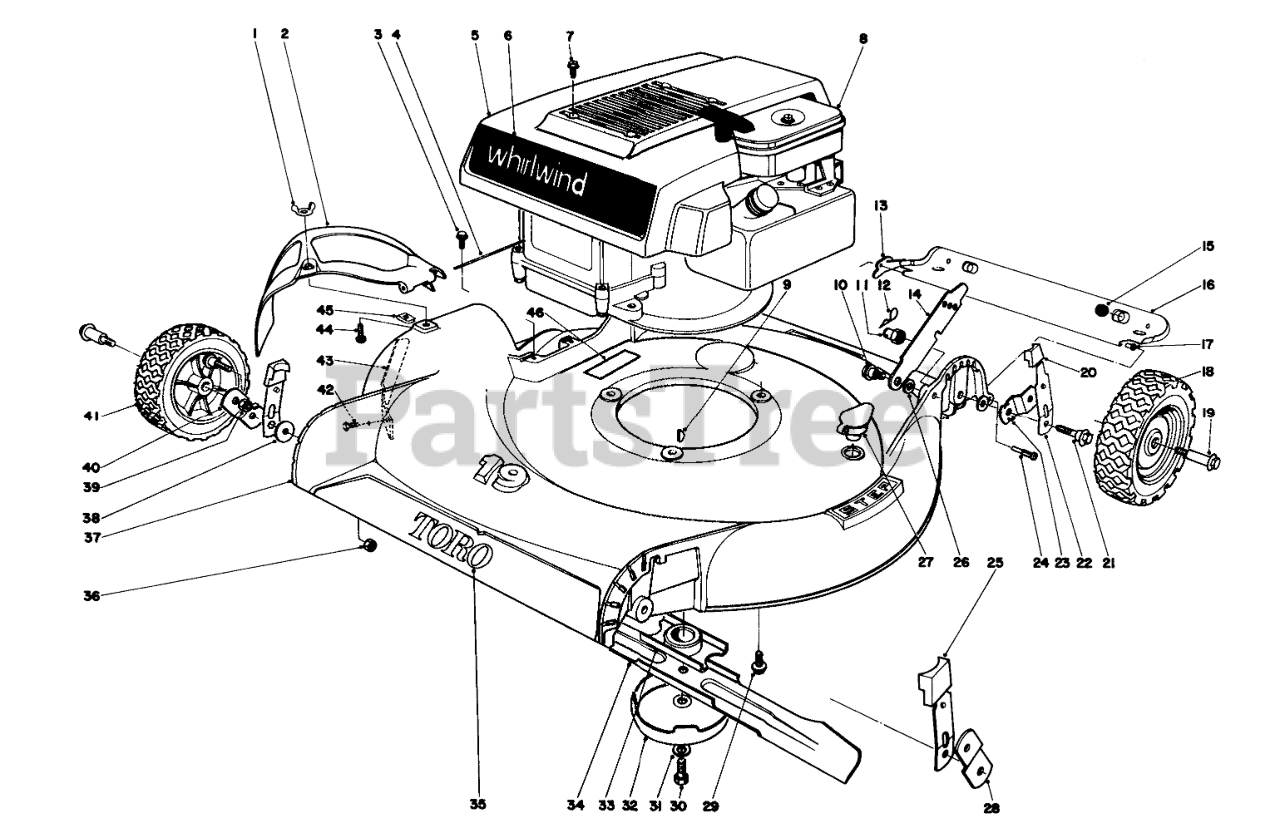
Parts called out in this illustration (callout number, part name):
1	NUT-WING SPECL
2	Deflector
3	SCREW
4	HINGE PIN
5	Shroud
6	Decal Whirlwind
7	8X1/2 SELF TAP SCREW
8	Engine (Model 16073)
9	KEY-WOODRUFF
10	SCREW-SHOULDER
11	HANDLE PIVOT NUT
12	Hair Pin Cotter
13	Restraint R.H.
14	Latch
15	SKID BUTTON
16	Safety Shield (Incl. Ref. #15 & 17)(Model 16073)
17	SAFTEY SHIELD BUSHING
18	WHEEL ASM 8
20	Arm Knob
21	PIVOT SCREW
22	Spring Arm
23	PIVOT ARM PLATED
24	SAFTEY SHIELD SCREW
25	Arm Knob
26	SPACER
27	WASHOUT PLUG
28	PIVOT ARM C PLTD
29	SCREW-HWHTF
30	SPECIAL SCREW
31	WASHER-LOCK
32	AntiScalp Cup
33	Blade Retailer
34	Blade
35	Decal Toro
36	Nut
37	Housing (Model 16073)
38	WASHER-PIVOT
39	Nut
40	PIVOT ARM D PLTD
41	WHEEL ASM 7
42	SCREW-HWH
43	Bar Safety
46	Decal
